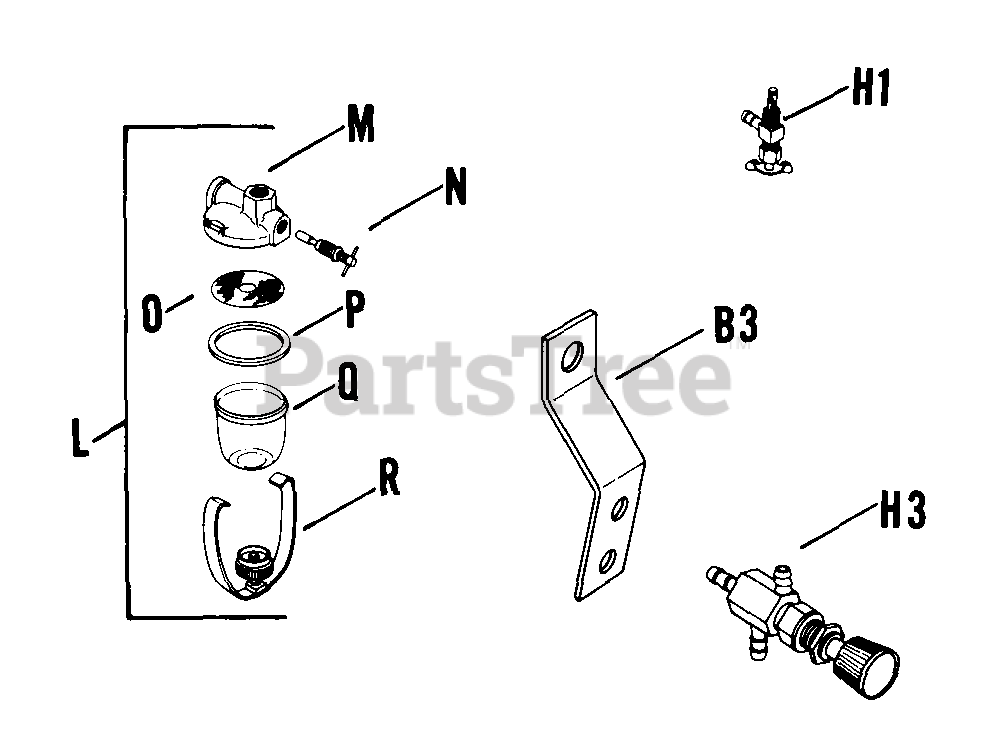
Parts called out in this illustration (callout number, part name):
L	KIT - USE 25 755 22
N	VALVE - DISCONTINUED
R	BAIL - DISCONTINUED
